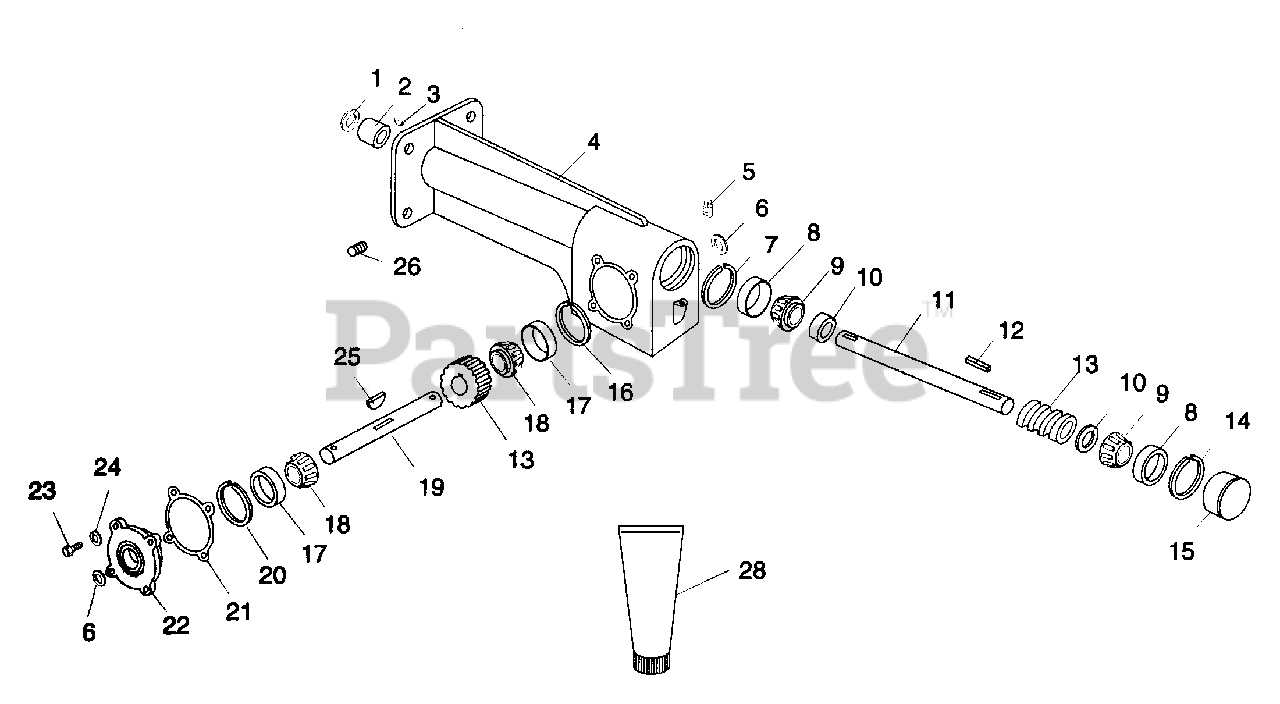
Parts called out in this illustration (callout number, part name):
1	SEAL .750X1.000X.125
2	BRG-NEEDLE .750X1.0X.62
3	KEY-WDRF .188X.875X.375 SAE11
4	WORM GEAR HOUSING
5	PIPE PLUG
6	SEAL 1.000X1.980X.375
7	RG-RTNG-INT 1.781X.062
8	BRG-CUP 1.781X.475
9	BRG-CONE .750X.61
10	BSHG, SPCR .755X1.12X.50 PM
11	WORM SHAFT
12	KEY-SQ .188X1.0X.188 SAE 8630
13	WORM GEAR AND WORM - KIT
14	RG-RTNG-INT 1.781X.062
14	RG-RTNG-INT 1.781X.057
14	RG-RTNG-INT 1.781X.052
14	RG-RTNG-INT 1.781X.047
14	RG-RTNG-INT 1.781X.042
15	DUST CAP
16	RG-RTNG-INT 1.969X.062
17	BRG-CUP1.980X.420
18	BRG-CONE 1.0X.58
19	TINE SHAFT
20	RG-RTNG-INT 1.969X.062
20	RG-RTNG-INT 1.969X.057
20	RG-RTNG-INT 1.969X.052
20	RG-RTNG-INT 1.969X.047
20	RG-RTNG-INT 1.969X.042
22	BEARING FLANGE
23	BOLT-HEX.31-18X.875 YWZC GR5
24	WSHR-LK .312X.097 HVY YWZC
25	KEY-WDRF .25X.875X.375 SAE A
26	BREATHER
28	ARIENS 16 OZ.BOTTLE OF L2 LUBE
